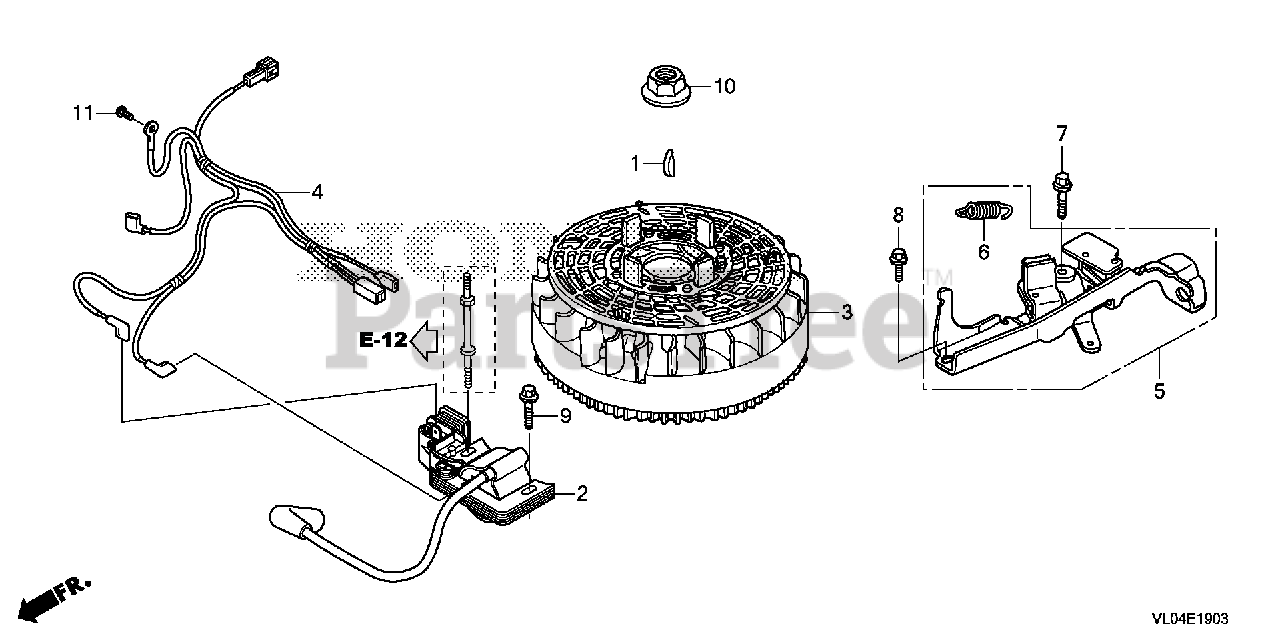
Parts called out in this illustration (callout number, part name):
1	KEY, SPECIAL WOODRUFF (25X18)
2	COIL ASSY., IGNITION
3	FLYWHEEL ASSY. (PHELON) (USE FOR IGN. COIL OF PHELON) (NA USE ALT:31105-Z0Y-922)
3	FLYWHEEL ASSY.
4	WIRE, COMBINATION
5	BRAKE SUB-ASSY.
6	SPRING, BRAKE LEVER
7	BOLT, FLANGE (6X23) (CT200)
8	BOLT, FLANGE (6X14) (CT200)
9	BOLT, FLANGE (6X23) (CT200)
10	NUT, SPECIAL (14MM)
11	SCREW, PAN (5X8)
